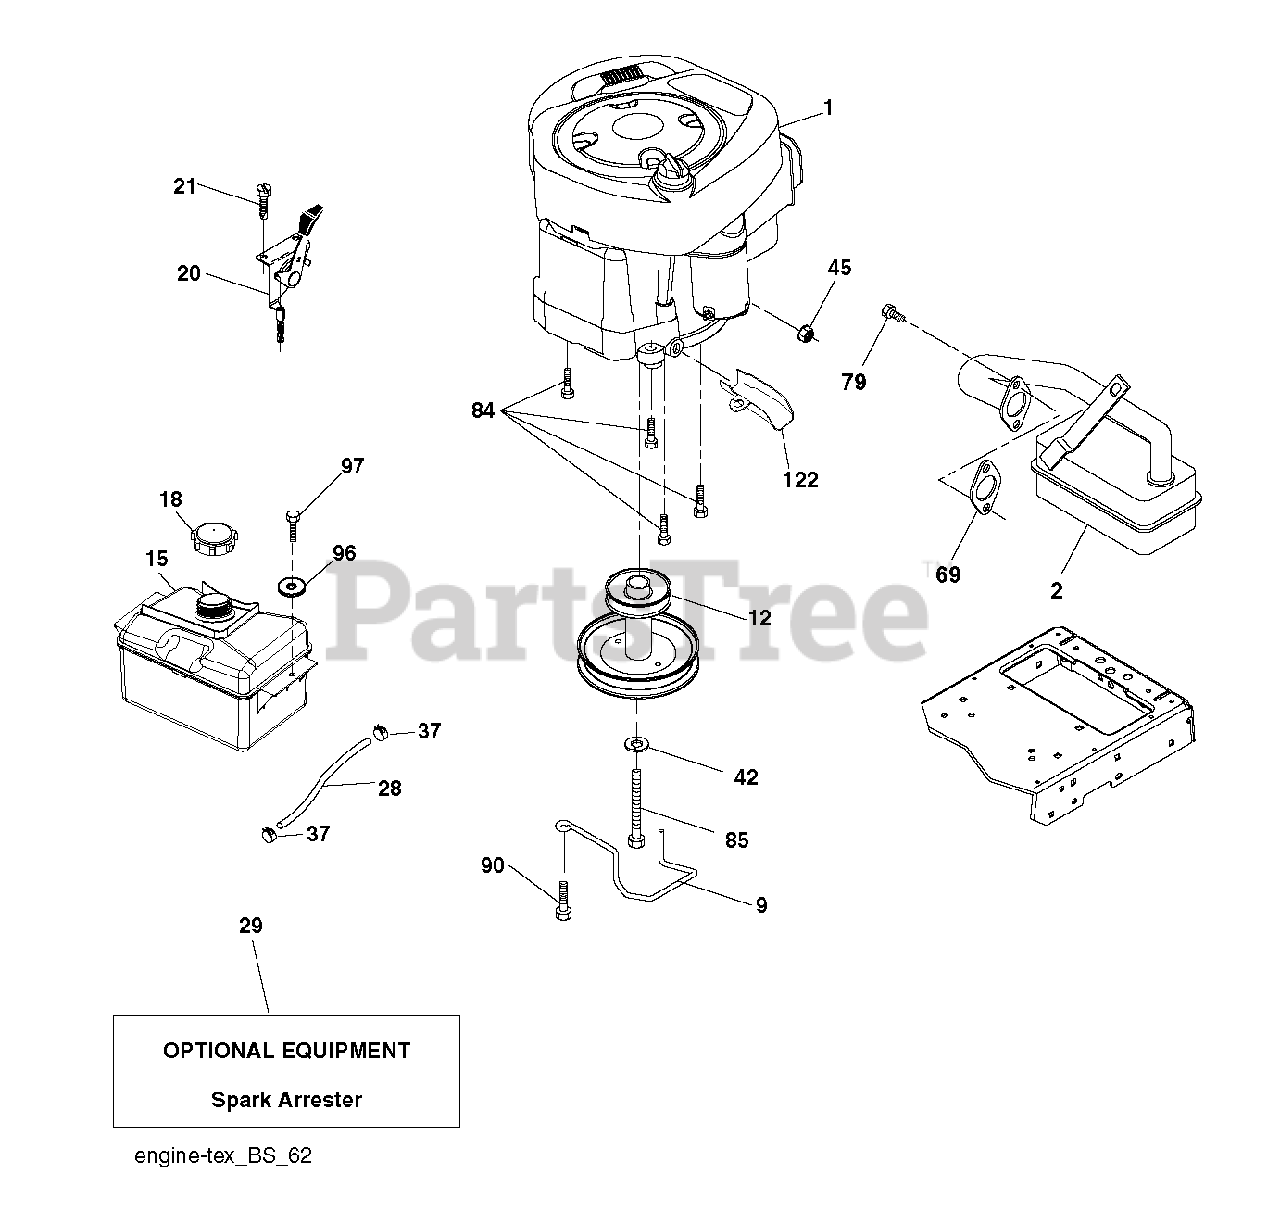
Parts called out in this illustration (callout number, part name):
9	KEEPER.BELT.ENGINE.3.25
12	PULLEY ENGINE
15	TANK FUEL FRT 1.5 GAL
18	CAP ASM.FUEL.2.25"FR.
20	CONTROL.TH/CK.C.
21	SCREW.#10 X 0.750.BOS THREAD
29	ARRESTER SPARK (OPTIONAL)
42	LOCKWASHER
45	NUT
69	REPL BY 532 27 22-93
79	SCREW.SOCKET HD.5/16-1
85	BOLT
90	SCREW 3/8-16X1
97	SCREW HEXWSHR 1/4-20X3/4
122	EXTENSION DRAIN OIL
